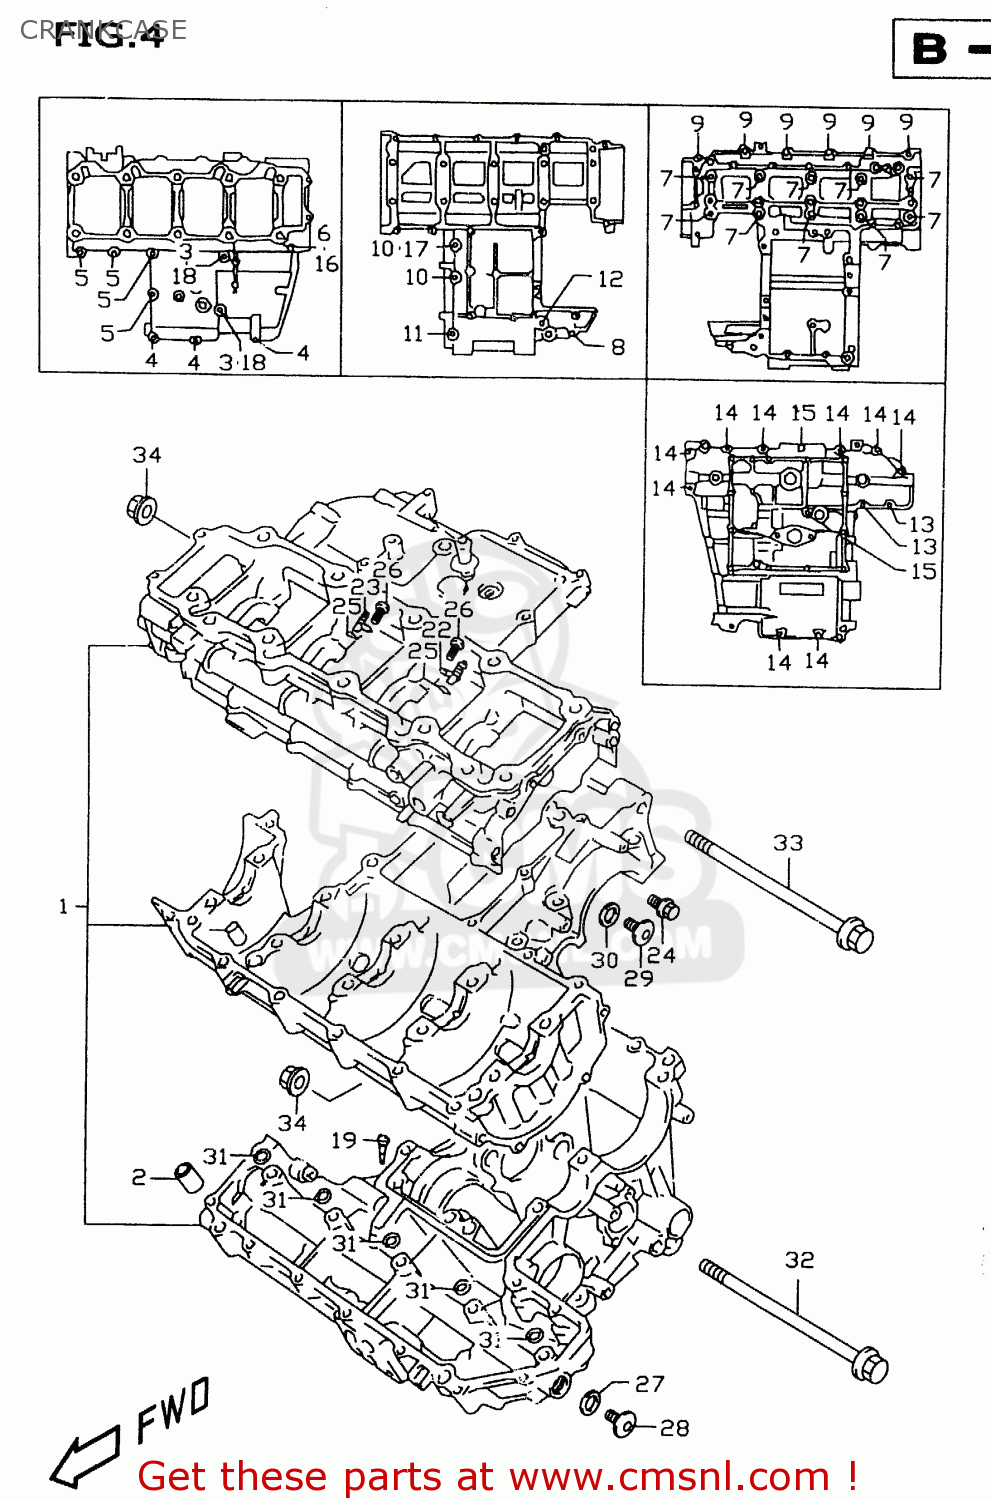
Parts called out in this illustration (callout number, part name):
1	CRANKCASE SET
2	PIN,CRANKCASE
3	BOLT(8X120)
4	BOLT
5	BOLT
6	BOLT
7	BOLT(9X95)
8	BOLT
9	BOLT
10	BOLT
11	BOLT
12	BOLT
13	BOLT,G/S SWITC
14	BOLT
15	BOLT
16	GASKET(5.8X11X1.2) (NAS)
17	GASKET(8.2X14X1) (NAS)
18	GASKET(8.2X14X1) (NAS)
19	JET(140)
20	BEARING,CRANK THRUST(GREEN)
21	BEARING,CRANK THRUST(RED)
22	JET,PISTON COOLINGR
23	JET,PISTON COOLING
24	JET,MAGNETO COOLING
25	O RING(D:1.2,ID:4)
26	BOLT(6X12)
27	GASKET(16X22X2) (NAS)
28	PLUG
29	PLUG,14X12
30	GASKET(13.8X18.8X4.8) (NAS)
31	O RING(D:1.9,ID:7.8)
32	BOLT(10X205)
33	BOLT(10X185)
34	NUT
